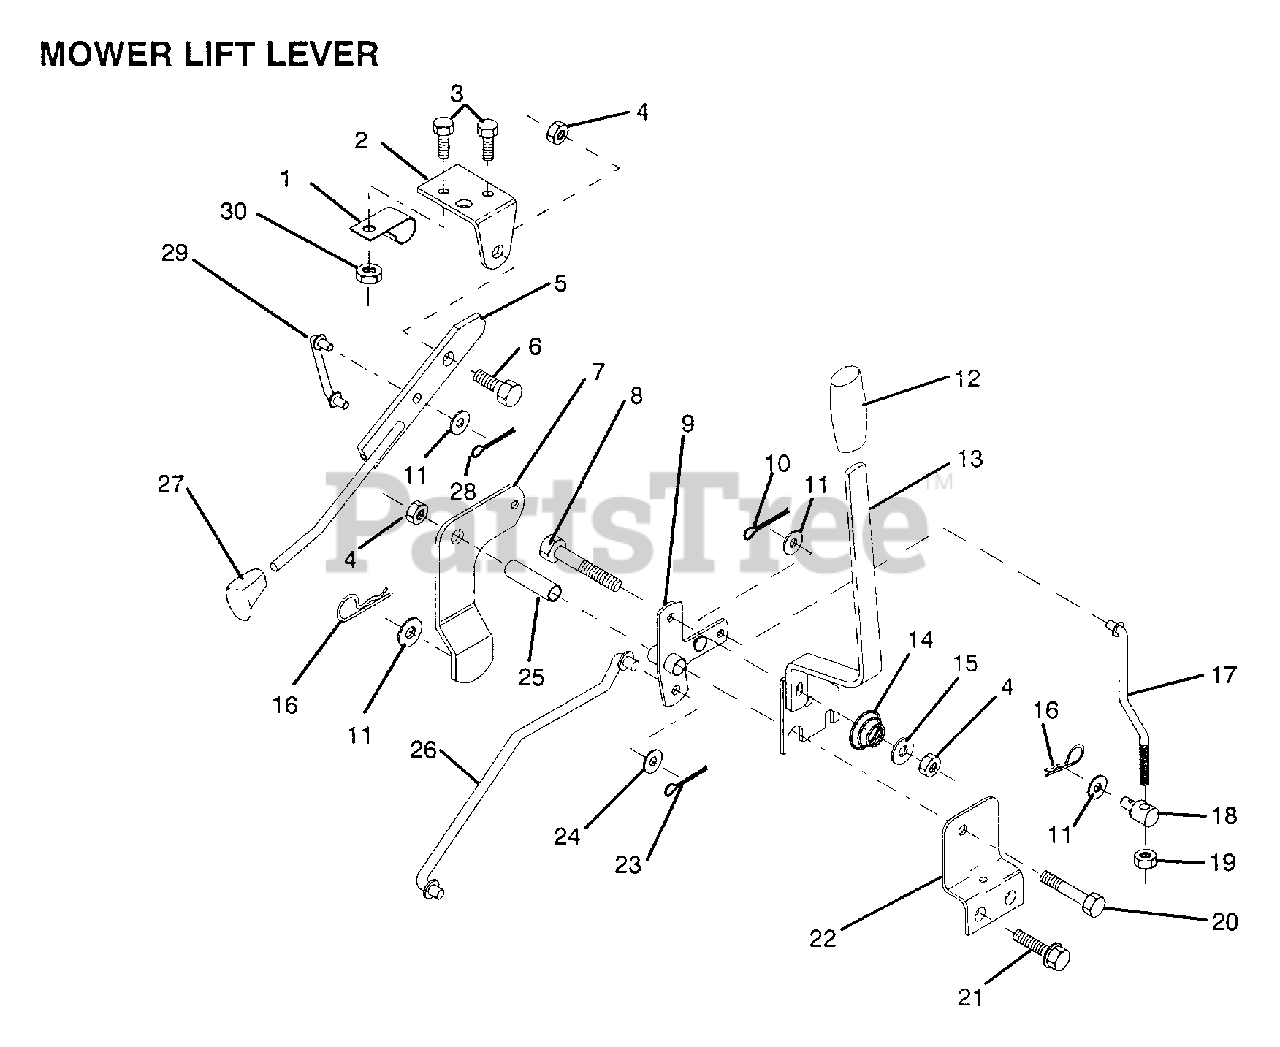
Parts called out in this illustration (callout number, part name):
1	"CLIP,INSULATOR"
2	BRKT CLUTCH
3	BOLT
5	CLUTCH LEVER AS
6	"BOLT, SHOULDER LT"
7	CLUTCH ARM ASS'Y
8	BOLT
9	"BELLCRANK,LIFT"
10	COTTER PIN
11	WASHER
12	GRIP HANDLE
13	"HDLE,LIFT T"
14	SPRING COMPRESSIO
15	WASHER T
16	SPRING.RETAINER
17	LINK FRT LIFT
19	NUT
20	BOLT
21	SCREW LT
22	"BRKT,MOWER HGT"
23	PIN COTTER 1/8
25	TUBE SPACER
26	"ROD,MOWER LIFT "
27	KNOB
29	"LINK,MOWER LIFT"
